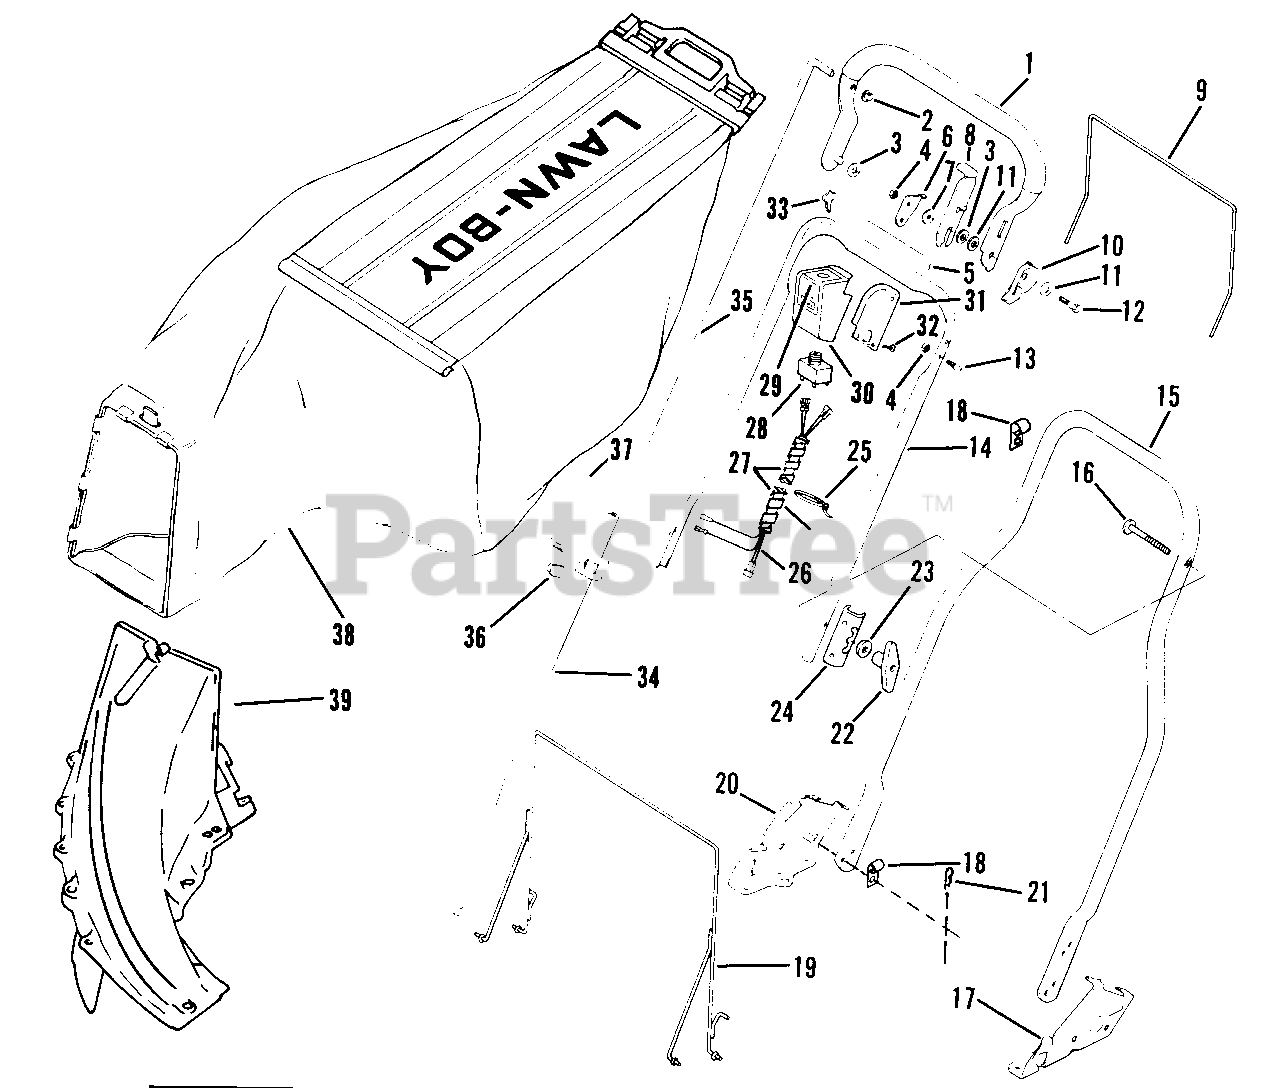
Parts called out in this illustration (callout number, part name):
1	Handle & Grip Assembly
2	Nut
3	Washer
4	Nut-Lock
5	Decal
6	Stop-Handle
7	Washer
8	Lever-Lockout
9	Hanger-Rear
10	Guard-Lever
11	Washer
12	Bolt-Shoulder
13	Screw-Stop
14	Handle-Center
15	Handle Section-Bottom
16	Screw
17	Bracket-Handle-L.H.
18	Clamp
19	Hanger Assembly-Front
20	Bracket-Handle-R.H.
21	Hair Pin
22	Knob
23	Washer-Curved
24	Bracket-Rear Hanger
25	Cable Tie
26	Wire Harness Assembly Switch
27	Spiral Tubing
28	Key Switch
29	Decal-Switch
30	Housing-Switch
31	Retaining Plate-Switch Housing
32	Screw
33	Key-Switch
34	Control Lever Assembly
35	Control Rod
36	Nut
37	Screw
38	Bag & Deflector Assembly
39	Chute Assembly
